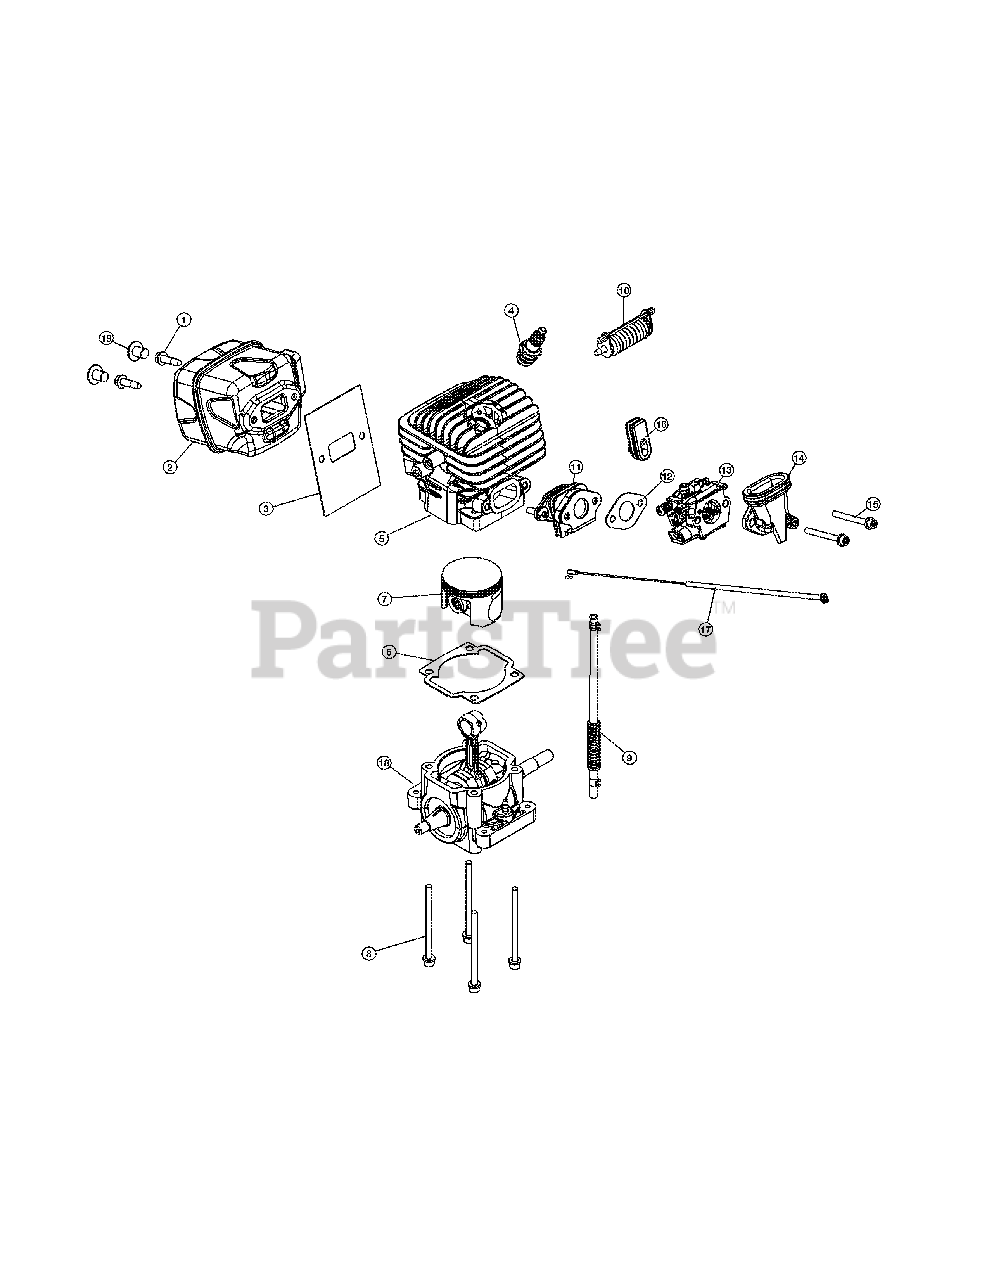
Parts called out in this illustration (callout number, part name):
1	Muffler Screw
2	Muffler Assembly (Incl.Ref No. 1, 3 & 19)
3	Muffler Gasket
4	Spark Plug
5	Cylinder Assembly (Incl.Ref No. 6, 8 & 10)
6	Cylinder Gasket
7	Piston Assembly
8	Cylinder Hardware
9	Breather Hose w/clamp
10	Isolator Assembly
11	Insulator Assembly
12	Carburetor Gasket
13	Carburetor
14	Boot & Bracket Assembly
15	Carburetor Hardware
17	Throttle Cable
18	Shortblock Assembly (Incl.Ref No. 4-10)
19	Muffler Plug
